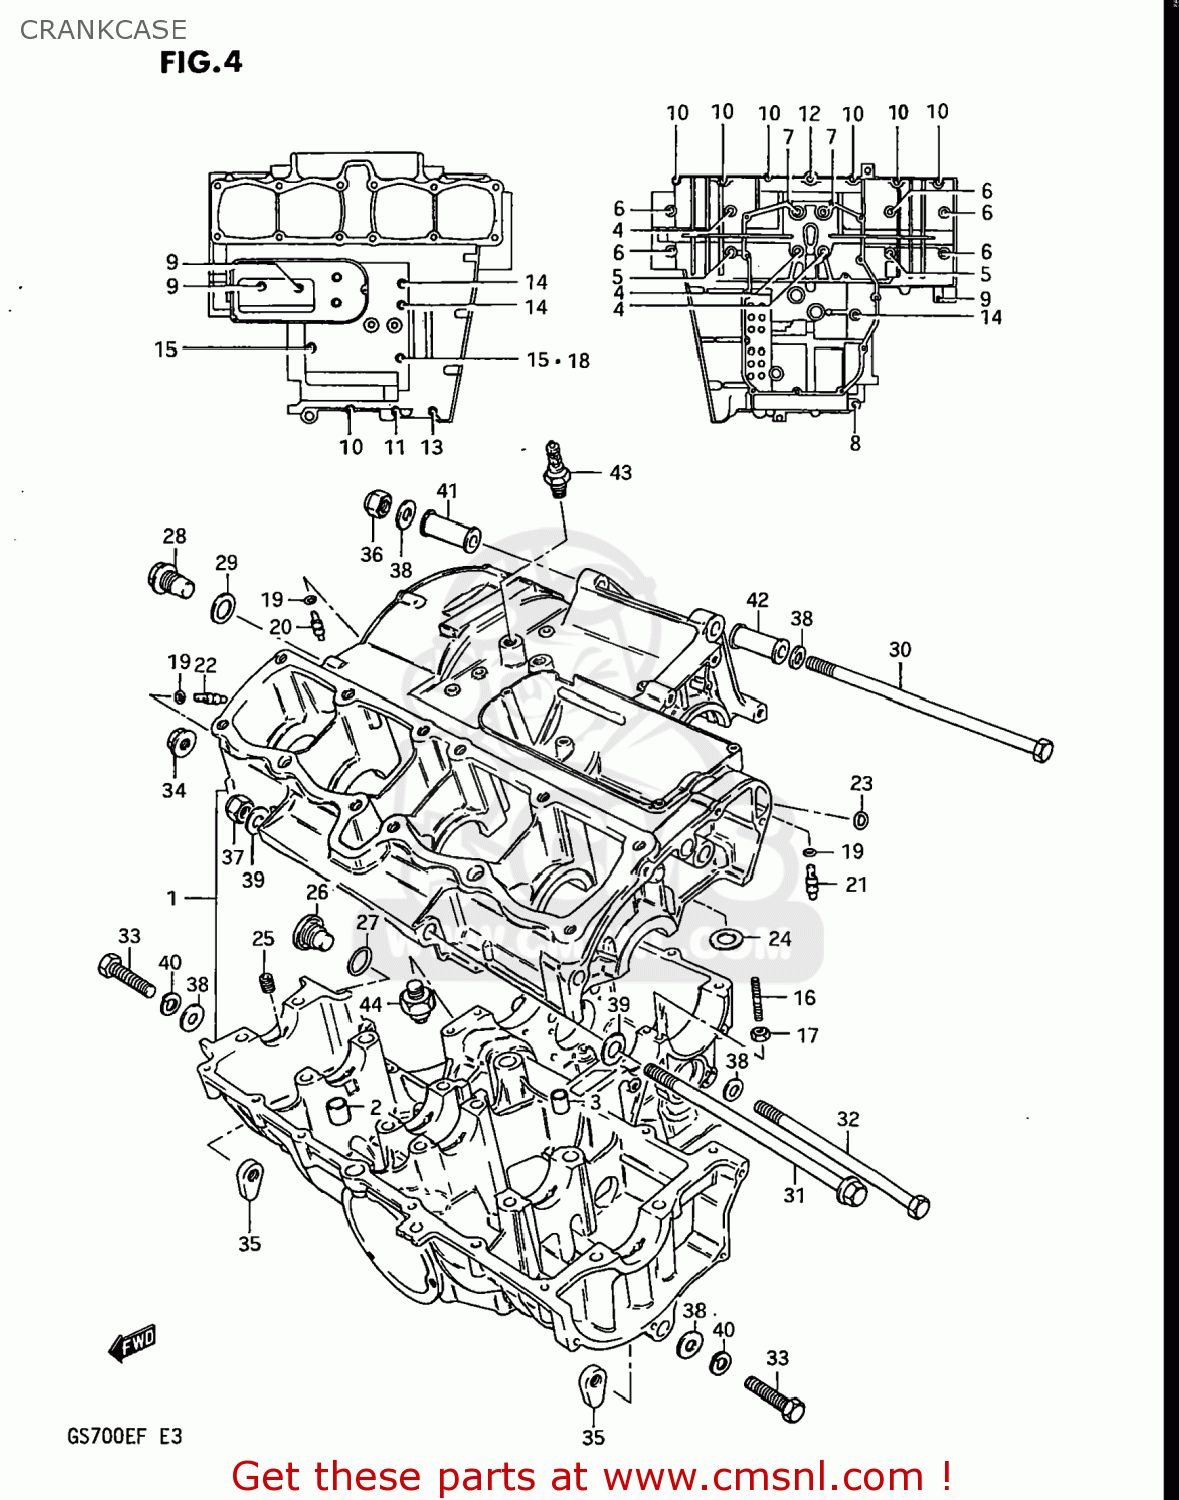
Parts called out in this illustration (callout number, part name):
1	CRANKCASE ASSEMBLY
2	PIN(10.4X13X22)
3	PIN (11X20)(SUS)
4	BOLT(8X120)
5	BOLT(8X135)
6	BOLT
7	BOLT
8	BOLT 8X60
9	BOLT 6X35
10	BOLT
11	BOLT
12	BOLT 6X50
13	BOLT 6X55
14	BOLT
15	BOLT (5X95)
16	STUD BOLT (6X45)
17	NUT
18	GASKET(6.2X13X1.2) (NAS)
19	O RING(D:1.2,ID:4)
20	JET,OIL GALLERY
21	JET(8)
22	JET,OIL
23	O RING(D:3.2,ID:12.9)
24	WASHER,THRUST
25	JET,AIR
26	PLUG
27	O RING(D:2.4,ID:16.8)
28	PLUG
29	GASKET(14X19.2X2) (NAS)
30	BOLT 10X255
31	BOLT 10X205
32	BOLT
33	BOLT
34	NUT 10MM
35	NUT
36	NUT
37	NUT
38	WASHER
39	WASHER (10.5X22X2.3)
40	LOCK WASHER
41	SPACER,ENGINE MOUNT
42	SPACER,ENGINE MOUNT(L:50)
43	GAUGE ASSEMBLY,OIL TEMPERATURE
44	SWITCH ASSEMBLY
